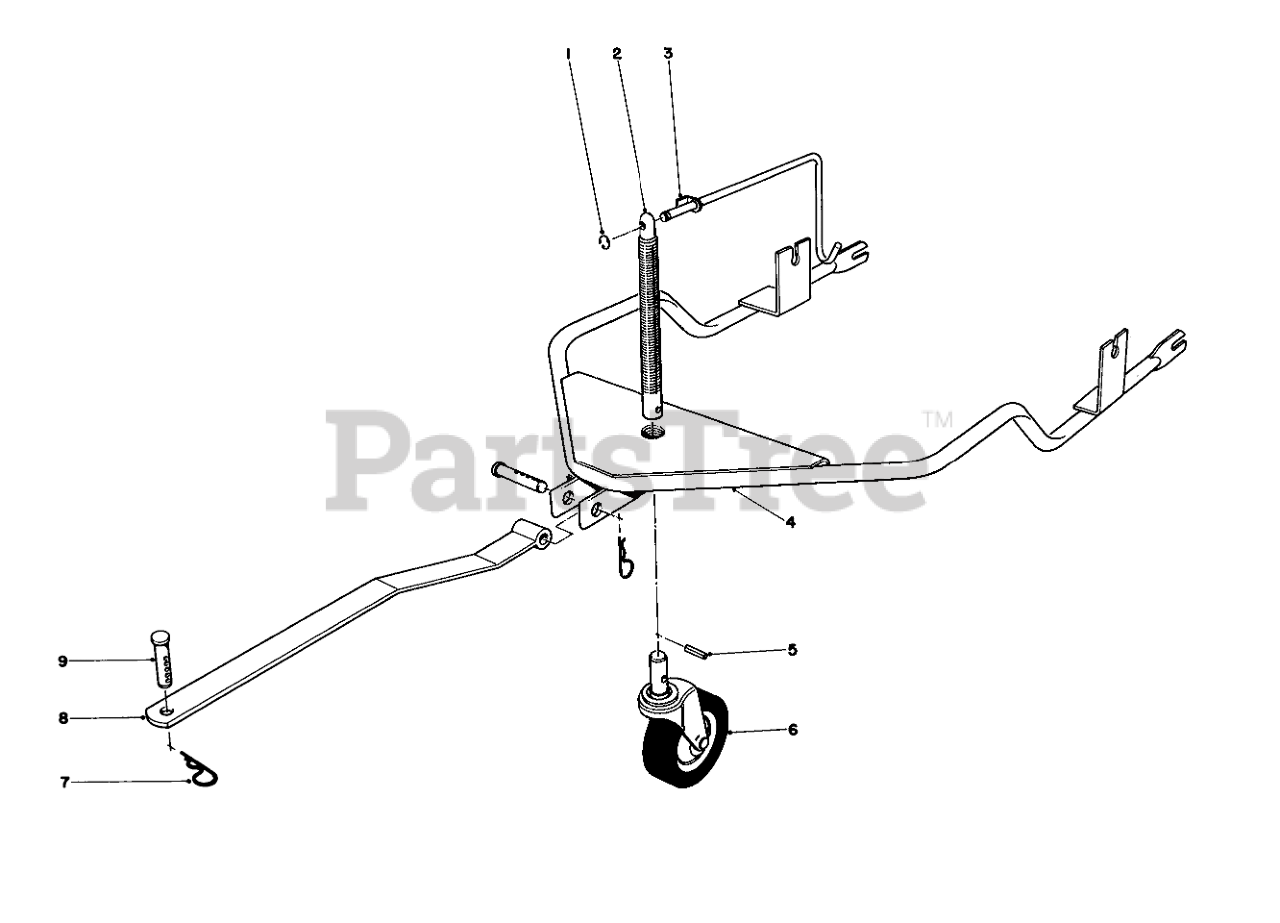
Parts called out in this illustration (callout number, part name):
1	Retaining Ring
2	Height Adjustment Bolt
3	Height Adjustment Lever
4	Hitch
5	PIN-SPRING
6	Caster Wheel
7	Hairpin Cotter
8	Tow Bar
9	Clevis Pin
